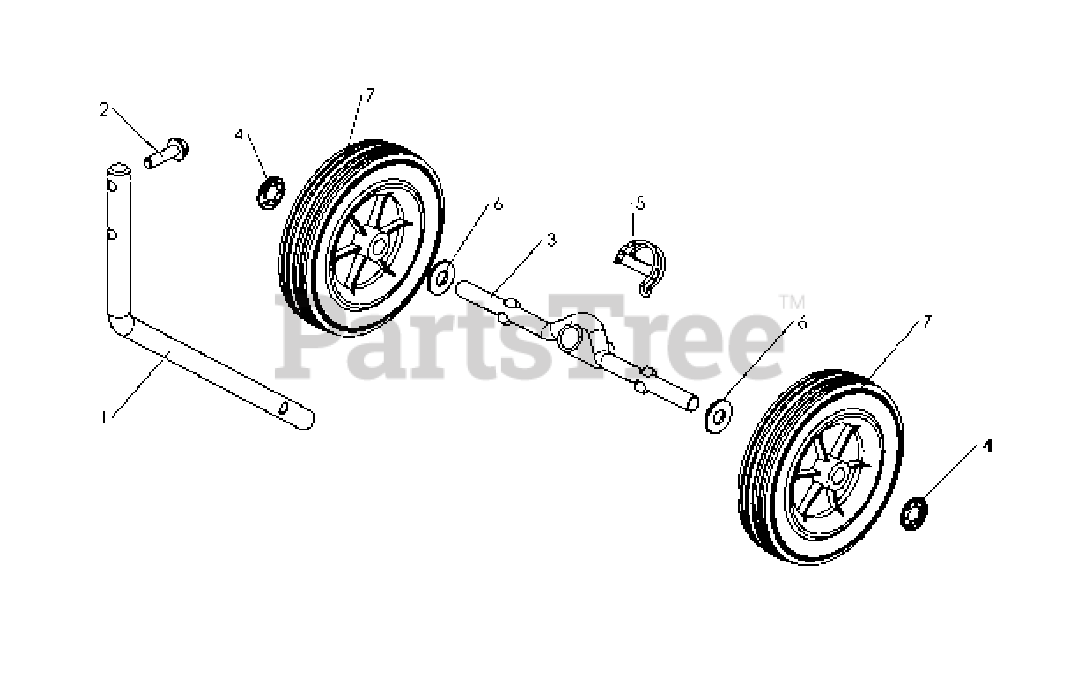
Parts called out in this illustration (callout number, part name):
4	WASHER 0300461201
5	PIN
6	WASHER
